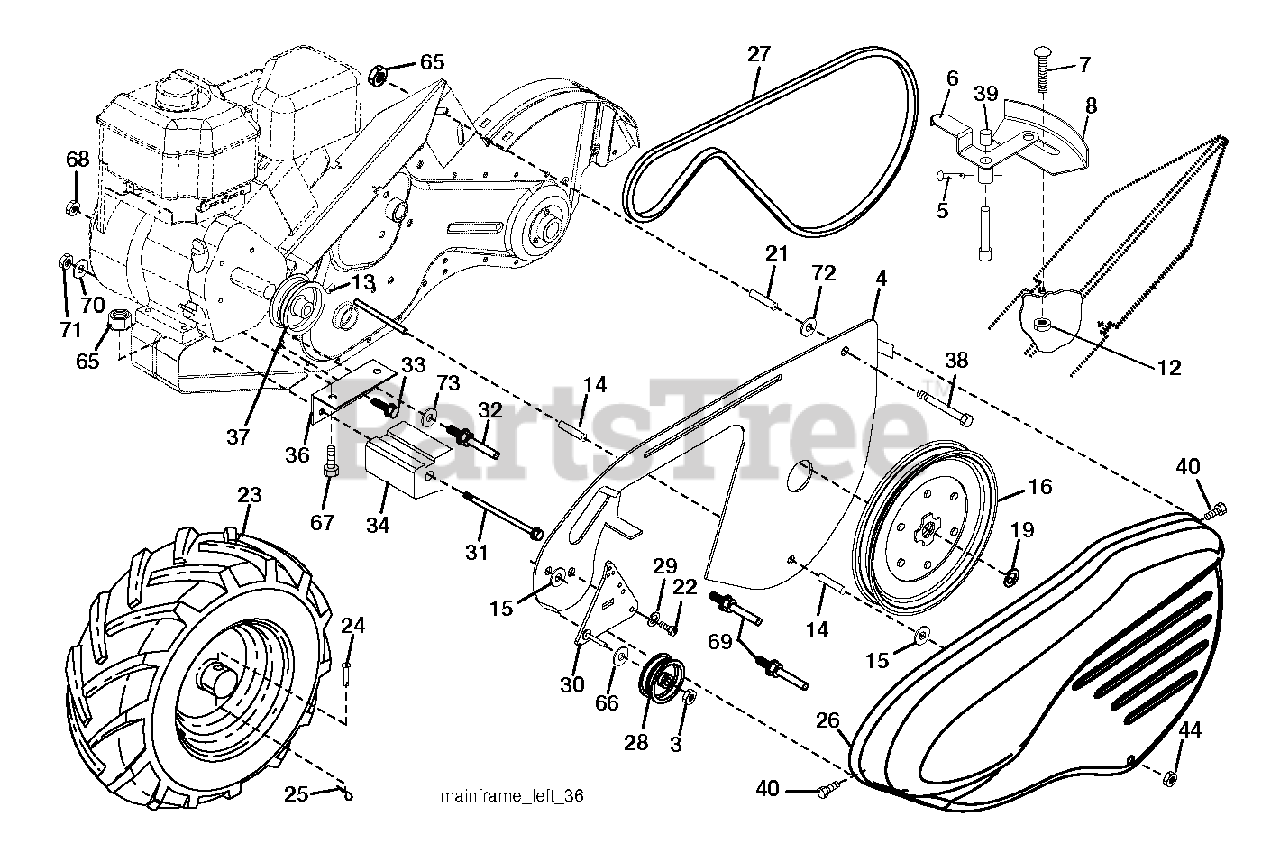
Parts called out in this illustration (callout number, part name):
3	LOCKNUT
4	SHIELD.INNER.BELT.GUARD.RT.BLA
5	PIN.SPIROL.FLARED
6	LEVER ASM CRT
8	PANEL.INDICATOR.SHIFT.BLACK
12	NUT
14	SPACER-SPLIT.327 X .42
15	WASHER.FLAT.34X1.38X22
16	SHEAVE, TRANSMISSION
19	RETAINING RING LT
21	SPACER SPLIT
23	WHEEL 16X4X8 DR TILLER LH.417
24	RIVET
25	RETAINER M
26	GUARD.BELT.TILLER.ORANGE
27	V-BELT
28	PULLEY-IDLER TI
30	BRACKET.IDLER.ASM.LONG
31	BOLT.FIN.HEX.3/8-16UNC X 11.5
32	SHIFT ARM CRT
33	BOLT
34	COUNTERWEIGHT.LH
36	BRACKET.REINFORCEMENT.LH.PNT
37	ENGINE PULLEY
38	BOLT
39	CAP.PLUNGER.BLACK
40	SCREW.HEX.WSH.SLT.#10-24X.50
44	NUT.71038.31-18.HEX.NYLOCK
65	LOCKNUT-FLANGE 5/16-18
66	WASHER
67	BOLT, HEX 5/16-18X1-3/4
69	KEEPER.BELT.ENGINE
70	WASHER
72	SPACER (2 2MC)
73	WASHER
